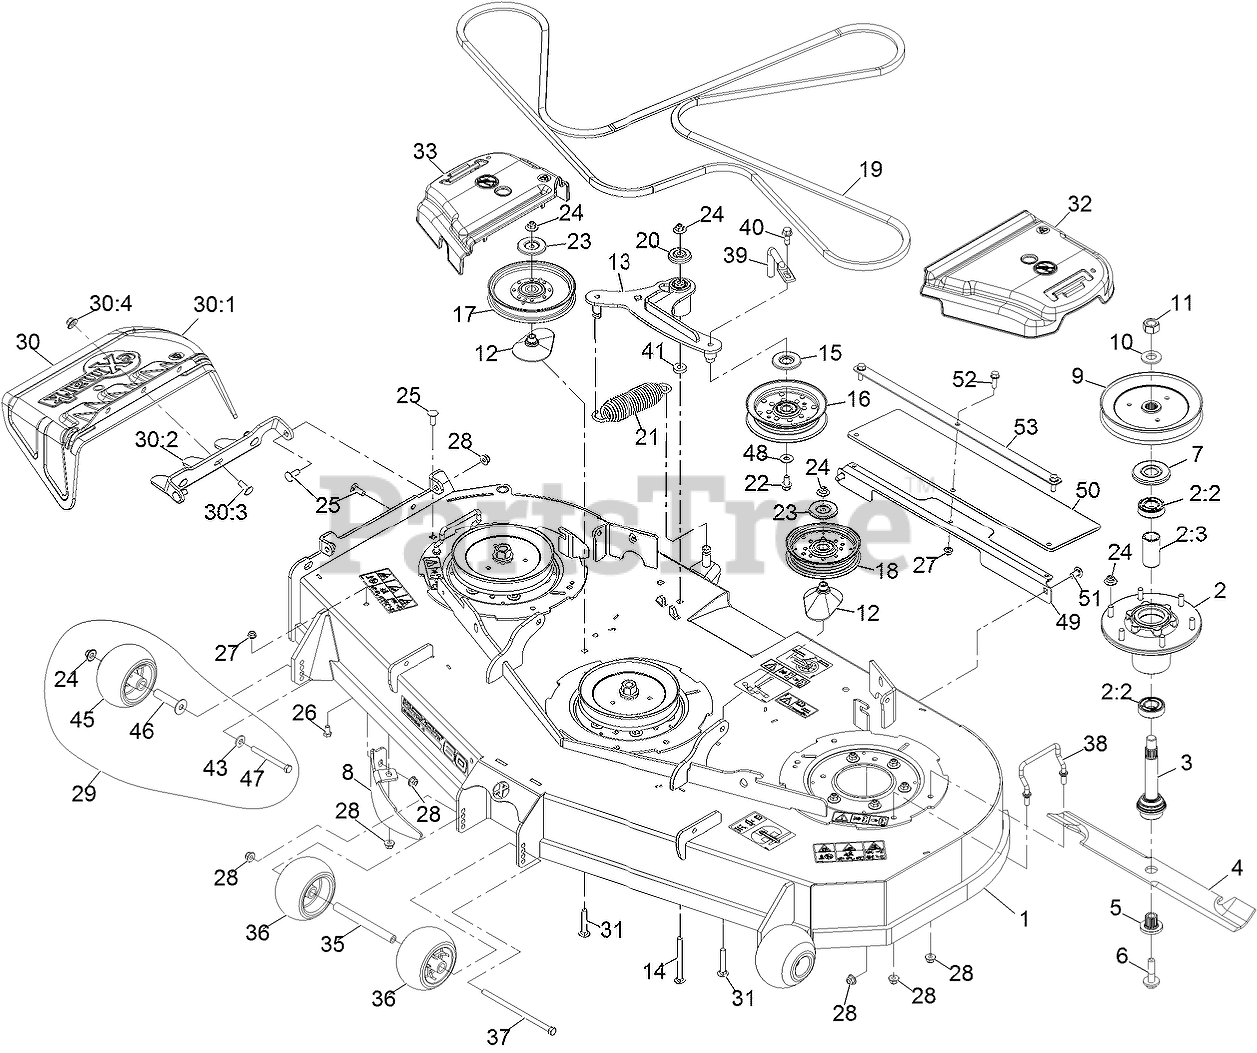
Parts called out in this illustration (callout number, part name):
1	ASM, 60" Deck W/ Decals
2	ASM-CUTTER HSG WITH BEARINGS
2:2	BEARING-BALL
2:3	SPACER-BEARING
3	ASM-SPINDLE AND SEAL
4	Blade-Extreme 2, 20.50"
5	BUSHING,SPLINED
6	SCREW,SEMS 1/2-20 X 2.19
7	GUARD,BEARING TOP .989
8	DOGLEG - LZ60
9	SHEAVE,BLADE DRIVE 7.25
11	NUT-HEX
12	SPACER-PULLEY
13	ASM, Deck Idler
14	SCREW-CARR
15	SHIELD-GUARD, DUST
16	IDLER-PULLEY, FLAT
17	IDLER-PULLEY
18	PULLEY-IDLER, FLAT
19	BELT, 5V
20	GUARD-TOP
21	SPRING-EXTENSION
22	SCREW-HHF
23	SHIELD-DUST
24	Nut-Nyloc 3/8-16 Flg
25	SCREW-CARR
26	SCREW-HH
27	NUT-HF, NI
28	NUT-HF, NI
29	KIT, ANTI-SCALP ROLLER
30	ASM,DISCHARGE CHUTE
30:1	CHUTE,DISCHARGE
30:2	BRACKET,DISCHARGE CHUTE
30:3	SCREW-CARR
30:4	Nut-Nyloc 3/8-16 Flg
31	Bolt-Carriage 3/8-16 X 2 1/4
32	COVER-BELT, LH
33	COVER-BELT, RH
35	SPACER-WHEEL
36	ROLLER-SCALP, ANTI
37	SCREW-HH
38	Wireform, Belt Cover
39	Guide, Belt
40	SCREW-HFH
43	WASHER-BELLEVILLE
45	ROLLER-SCALP, ANTI
46	AXLE, ROLLER
47	SCREW-HH 3/8-16 X 3 3/4 GR 8
48	WASHER-FLAT
49	Brkt, Heat Deflector
50	Shield, Heat
51	SCREW-CARR
52	SCREW-HHF
53	Brkt-Heat Deflector, Top
